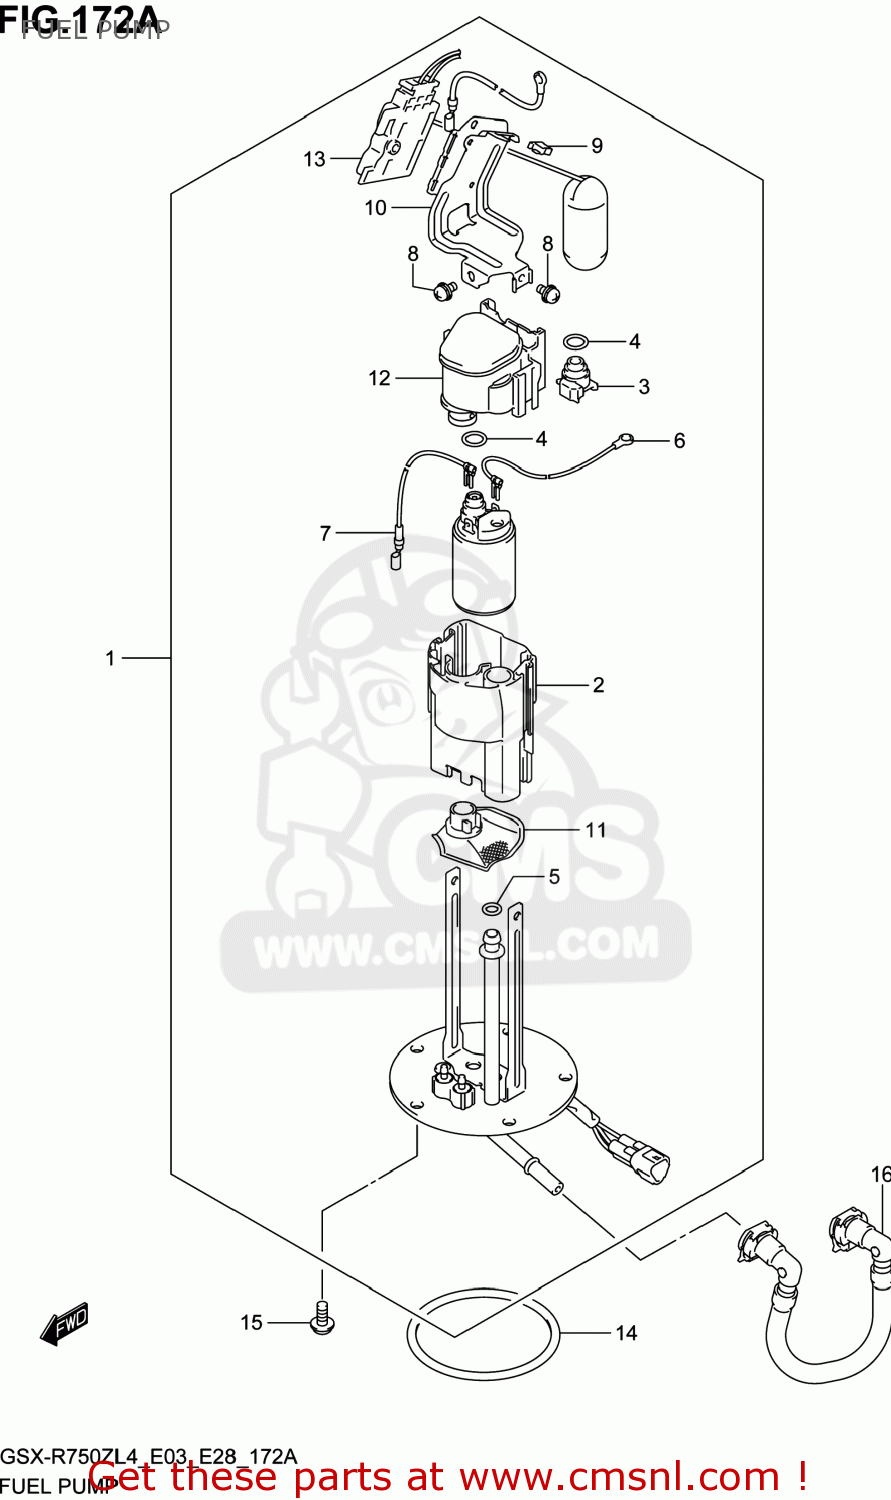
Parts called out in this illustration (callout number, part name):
1	PUMP ASSY,FUEL
2	CUP
3	JOINT
4	O RING
5	O RING
6	WIRE,EARTH
7	WIRE,LEAD
8	SCREW
9	SADDLE,EDGE
10	BRACKET,GAUGE
11	STRAINER
12	REGULATOR,FUEL
13	GAUGE ASSY,FUEL LEVEL
14	O RING,FUEL PUMP
15	BOLT
16	HOSE,FUEL
